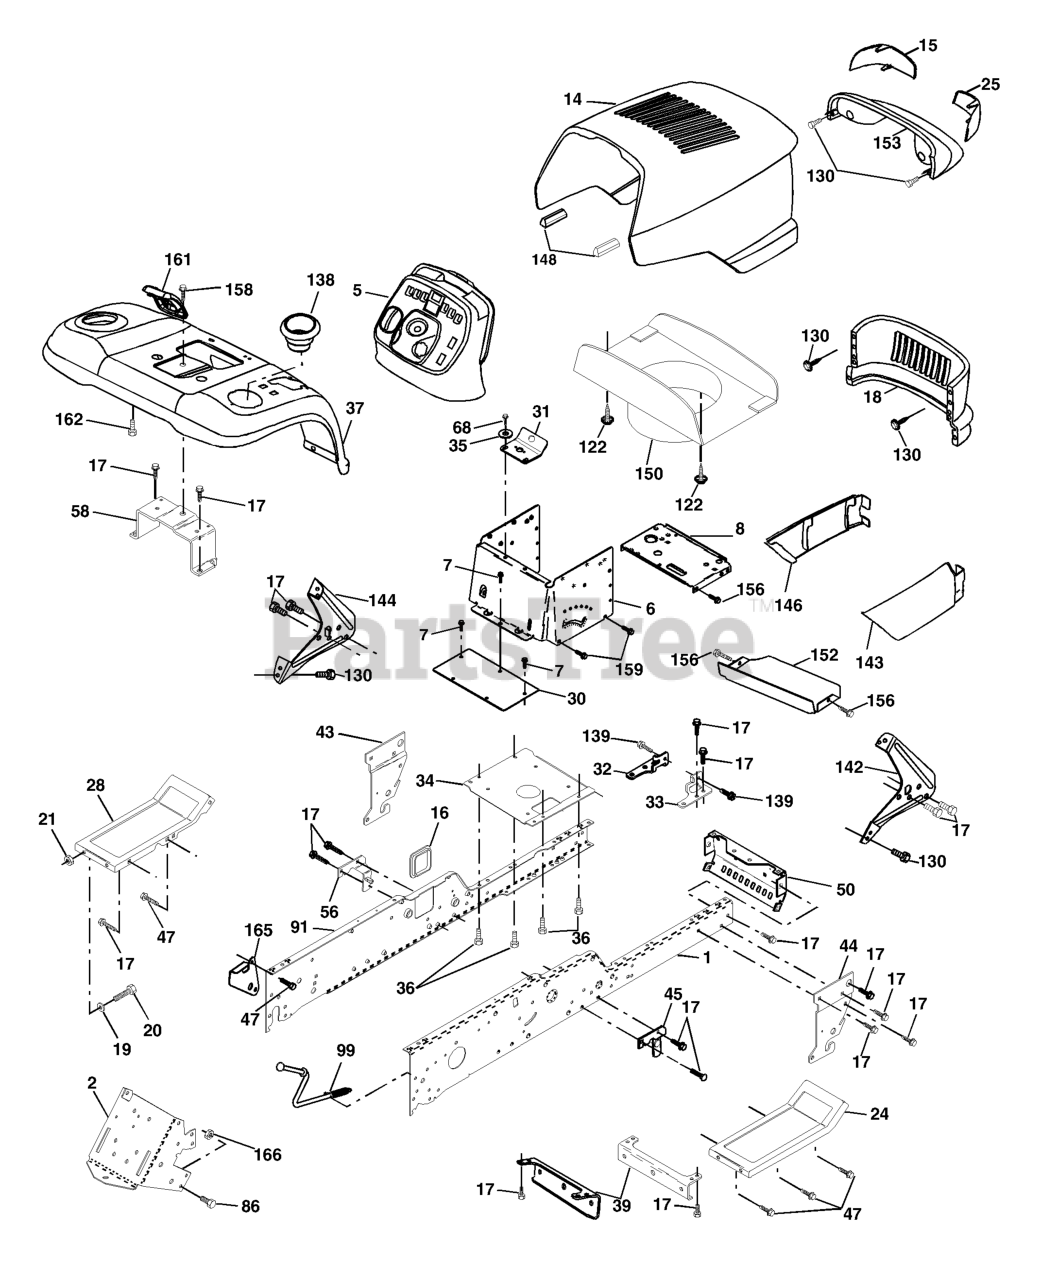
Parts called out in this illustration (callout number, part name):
1	KIT.RAIL.CHASS.RH.GT
2	DRAWBAR, GT
5	DASH, PLASTIC
6	DASH VGT, LOWER
7	SCREW
8	SUPPORT, BATTERY
14	HOOD ASM.
15	LENS LH
16	COVER ACCESS
17	SCREW 3/8-16X3/4
18	GRILLE
19	WASHER
20	BOLT
21	NUT
24	FOOTREST PNT RH
25	LENS RH
28	FOOTREST PNT LH
30	SADDLE.HYDRO.95
31	BRACKET SUPT 1-PC VGT STEERING
34	PLATE ASM ENG CHASSIS
35	WASHER
36	SCREW 5/16"
37	FENDER, PNT
39	BRACKET AXLE, FRONT
43	FRONT SUSPENSION BRKT LH
44	FRONT SUSPENSION BRKT RH
45	BRACKET, ASM., SUSP CHASSIS RH
47	SCREW LT
50	BRACKET, CHASSIS FRONT
56	BRACKET ASM., SUSP CHASSIS LH
58	BRACKET ASM., FENDER
68	Screw, 5/16-18 x 1/2
91	KIT.RAIL.CHASS.LH.GT
99	ROD ASM, BYPASS
122	SCREW.HEX.WS.HD.8-18 X 7/8
130	SCREW
138	CUPHOLDER
139	BOLT, SHOULDER 5/16-18
142	BRACKET DASH STEALTH(R)
143	SKIRT GRILLE RH
144	BRACKET DASH STEALTH LH
146	SKIRT GRILLE LH
148	EXTRUSION BUMPER (3 2) (2 2)
150	DUCT HEAT HOOD
152	BROWNING SHIELD
153	LIGHT ASM.
156	SCREW
158	SCREW 3/8-16X1/2
159	SCREW, 3/8-16X3/4
161	CONSOL.FUEL.WINDOW.BLACK
162	SCREW.HI-LO.CONSOLE
165	BRACKET SUPPORT TANK
166	Nut, Lock Hex 7/16 Unc
